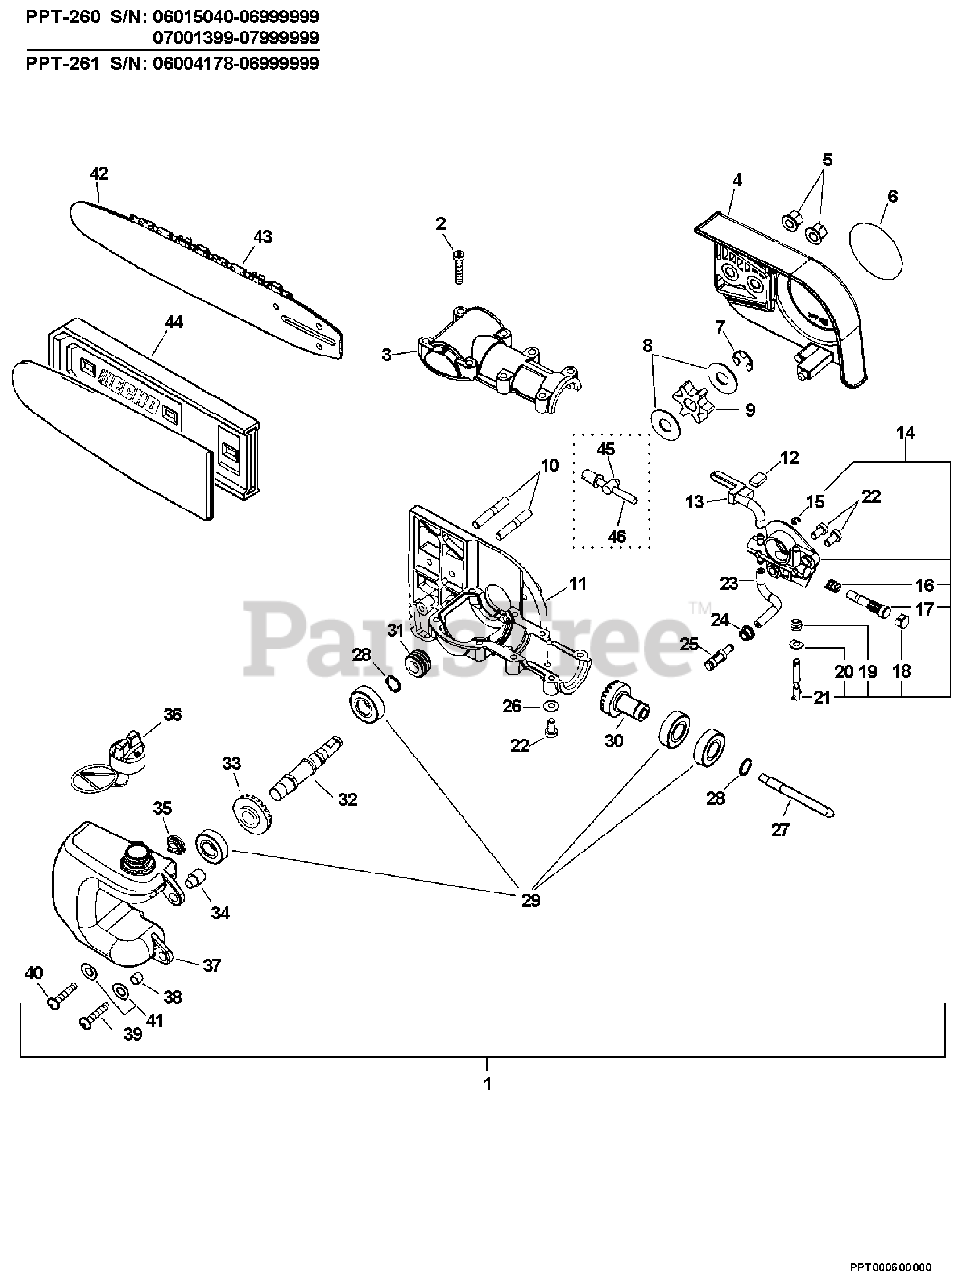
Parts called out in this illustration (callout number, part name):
1	OILER/GEAR CASE ASSY
2	SCREW - 5X25
3	CASE, GEAR - UPPER
4	GUARD, SPROCKET
5	NUT - 6 -- FLANGE
6	LABEL - ECHO
7	RING, RETAINING
9	SPROCKET, DRIVE
10	STUD - 6
11	GEAR CASE ASSY - LOWER
12	PAD, FOAM
13	PIPE, OIL OUTLET
14	AUTO-OILER ASSY
15	RING, RETAINING
16	SPRING, PLUNGER
17	PLUNGER ASSY
18	CAP, OIL PUMP
21	NEEDLE, ADJUST
22	SCREW - 5X10
23	PIPE - 3X6X75 -- BLACK
24	GROMMET
25	FILTER, OIL
26	WASHER - 5
27	CONNECTOR, SHAFT
28	RING, RETAINING - 12
29	BEARING, BALL - 6001
30	GEAR - BEVEL
31	GEAR - WORM
32	GEAR - SHAFT
33	GEAR - BEVEL
36	CAP ASSY
37	TANK, OIL
39	SCREW - 5X16
40	SCREW - 5X25
41	WASHER - 5
42	GUIDE BAR - 12" (30cm) Intenz
43	SAW CHAIN - 12" (30cm)
44	COVER, GUIDE BAR - 12" (30cm)
45	TENSIONER, CHAIN
46	SCREW, TENSIONER
